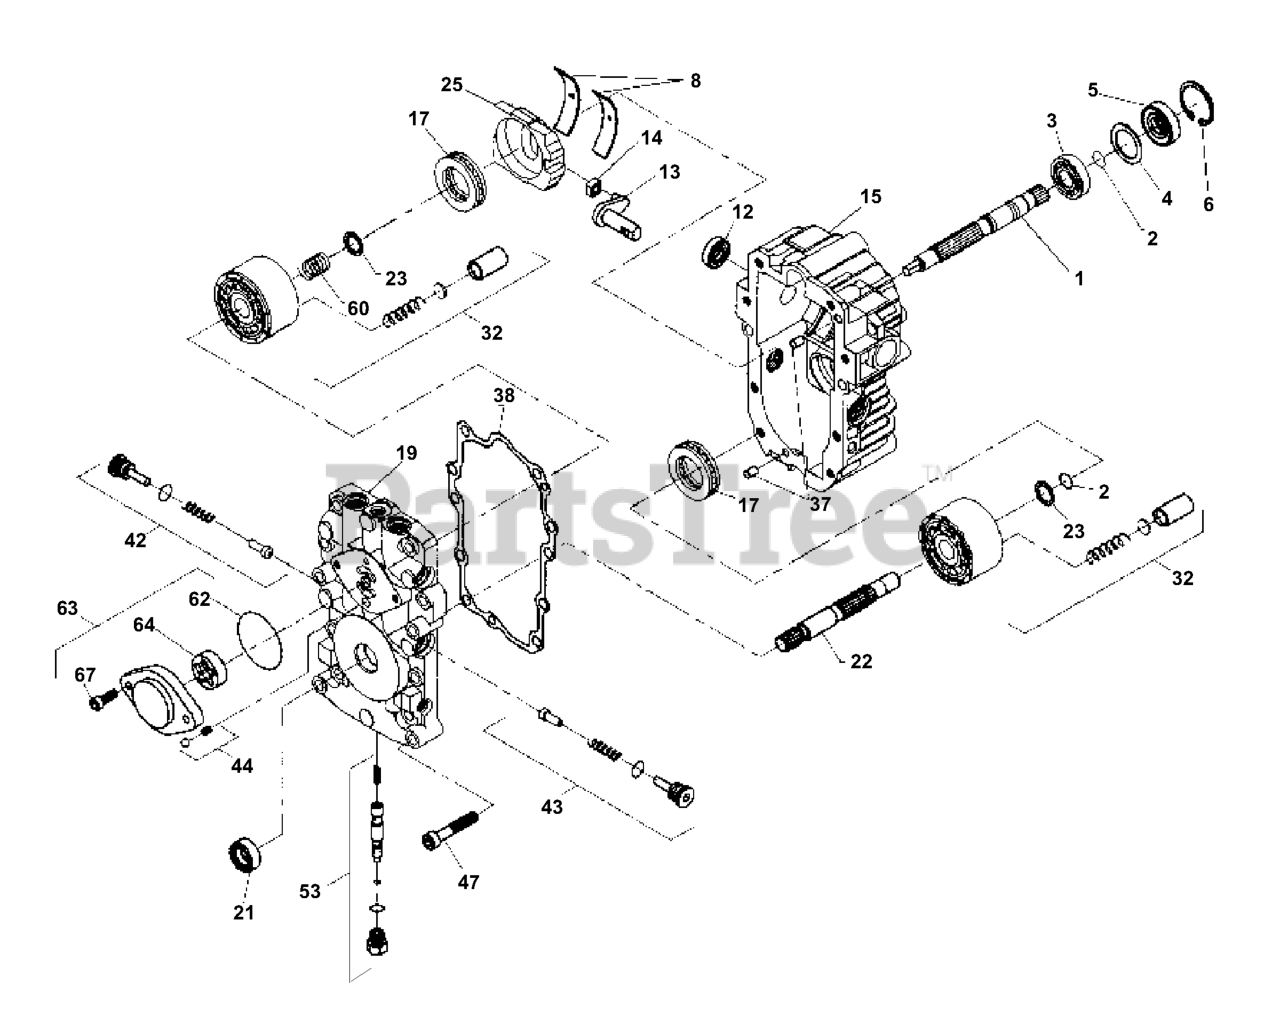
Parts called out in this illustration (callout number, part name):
1	SHAFT, PUMP
2	RETAINIANG RING
3	BALL BEARING 2003043
5	SEAL LIP
6	RETAINING PIN
8	CRADLE BEARING
13	TRUNION ARM
14	GUIDE 2000015 HYD
15	HOUSING KIT, TRANSMISSION
17	BALL BEARING
19	CENTER SECTION KIT
21	LIP SEAL 9008000-0127
22	SHAFT MOTOR 2003034
23	Washer, Block Thrust
25	SWASHPLATE,VARIAB
32	Block Assembly
38	GASKET 2003060
42	CHECK VALVE KIT 2510050
43	CHECK VALVE KIT 2510050
44	CHARGE RELIEF KIT 2510011
53	KIT,BYPASS VALVE(2513011)
60	Block Spring
62	O-RING.HYDRO GEAR.9004101-1340
63	CHARGE PUMP KIT
64	GEROTOR ASSEMBLY
67	SCREW, SOCKET HEAD CAP
